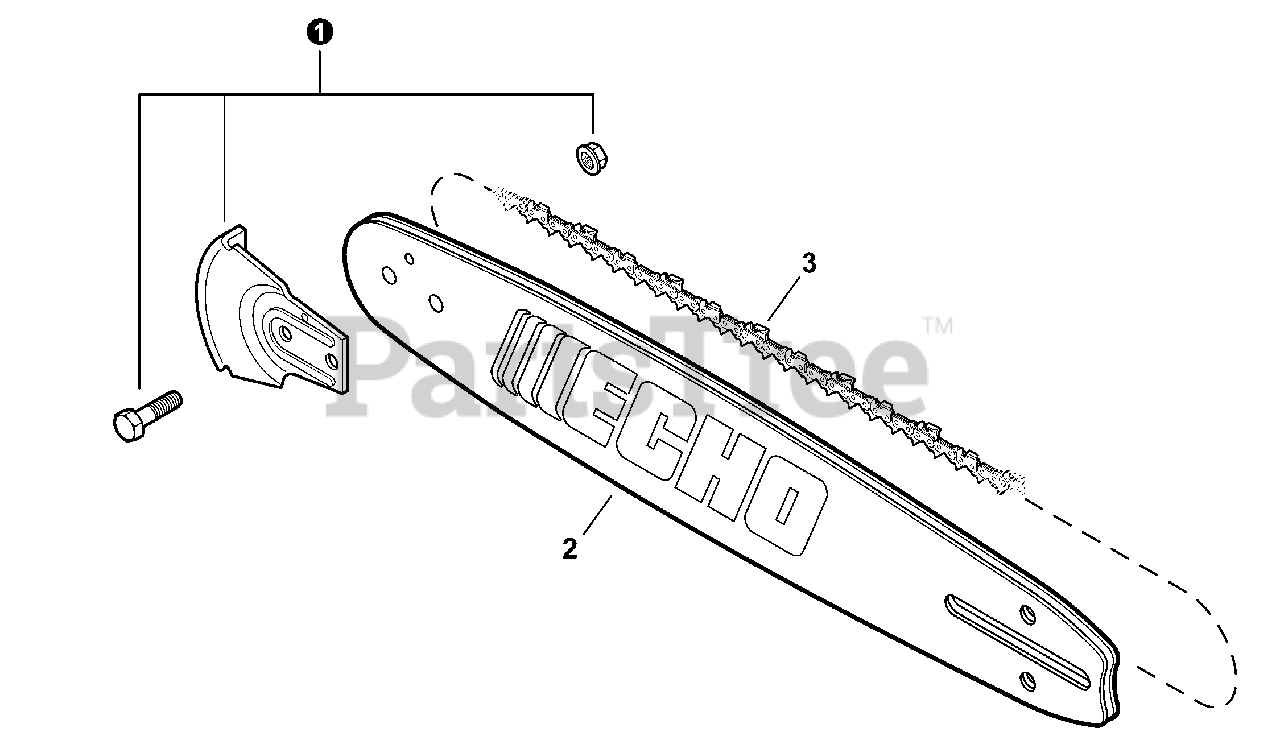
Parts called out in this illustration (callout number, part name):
1	KICK GUARD KIT
2	GUIDE BAR, 14" DOUBLE-GUARD
2	GUIDE BAR, 16" DOUBLE-GUARD
2	GUIDE BAR, 18" DOUBLE-GUARD
3	SAW CHAIN 14"
3	SAW CHAIN 16"
3	SAW CHAIN 18"
